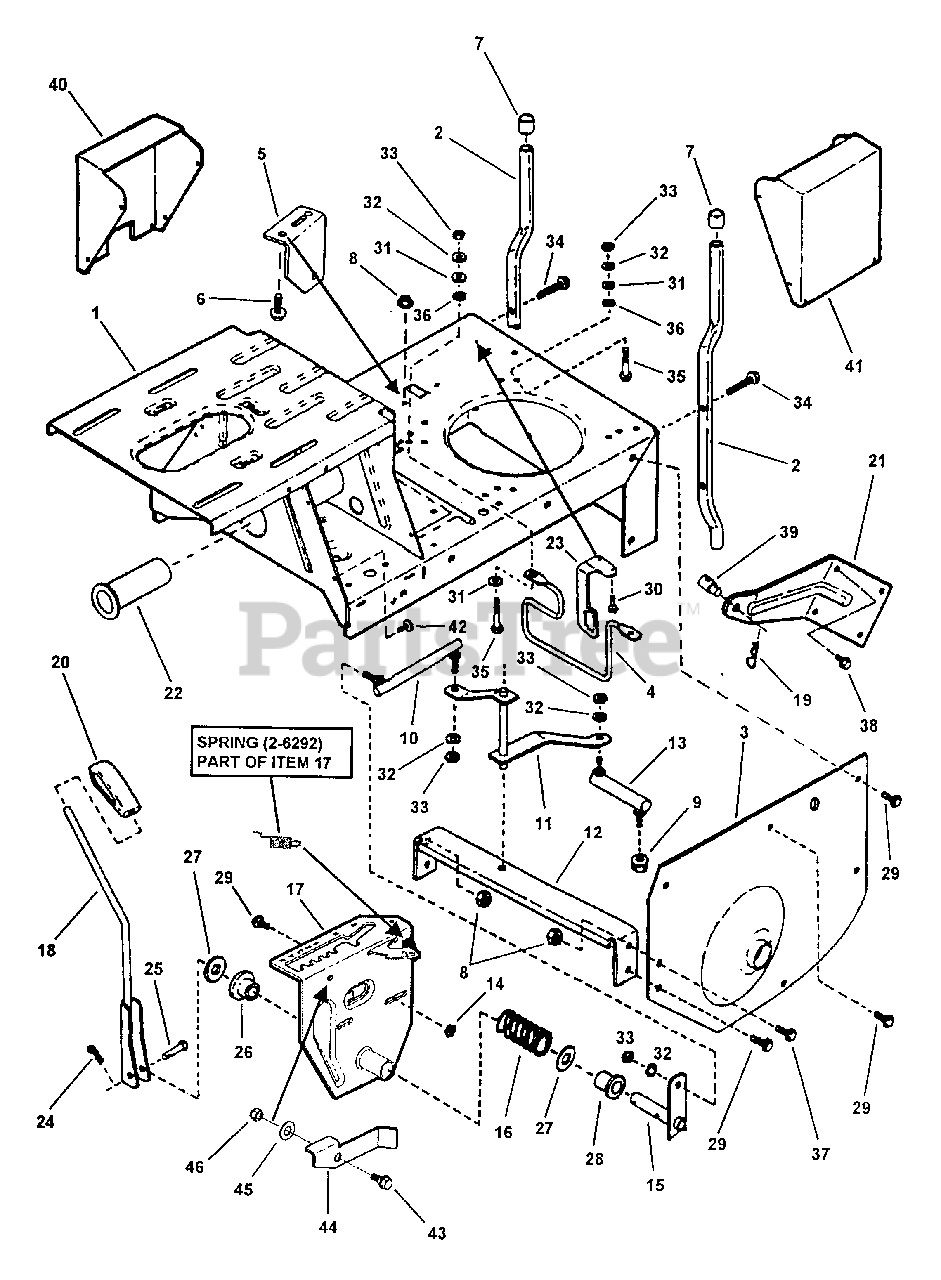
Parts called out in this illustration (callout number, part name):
1	CASE, Main (Standard)
2	BUMPER, Rear
3	FENDER, Left Hand
4	GUIDE, Belt
5	BRACKET, Drive Support
6	BOLT, 5/16-18 X 3/4" Hex Flange Lock
7	CAP, Bumper
8	NUT, 5/16-18 Hex Flange Lock
9	NUT, 5/16-24 Hex Flange Lock
10	LINK, Shift (Long)
11	ARM, Shift
12	BRACE, Cross
13	LINK, Shift (Short)
14	NUT, 5/16-18 Hex
15	ARM, Shift Handle
16	SPRING, Shift Handle
17	ASSEMBLY, Shift Detent
18	HANDLE, Shift
19	HAIRPIN, 3/32 X 1-1/2"
20	GRIP, Shift Handle
21	WING, Rear
22	BUSHING, Pilot
23	BRACKET, Switch
24	PIN, 3/32 x 3/4" Cotter
25	PIN, 1/4 x 1-3/4" Tapered Clevis
26	BUSHING, Nylon
27	WASHER, Thrust
28	BUSHING, Nylon
29	SCREW, 5/16-18 x 5/8" Self-Tap
30	SCREW, 10-32 x 1/4" Hex Washer Self-Tap
31	WASHER, 5/16" Flat
32	WASHER, 5/16" Split Lock
33	NUT, 5/16-24 Hex
34	SCREW, 5/16-18 x 1-1/2" Self-Tap
35	SCREW, 5/16-24 x 1-1/2" Hex Head Cap
36	RETAINER, 5/16 Bolt
37	SCREW, 5/16-18 x 3/4" Hex Head Cap
38	SCREW, 5/16-18 X 3/4" Hex Self-Tap
39	SWIVEL
40	COVER, Switch
41	COVER, Battery
42	FASTENER, 1/4 x 3/4" Ratchet
43	BOLT, 5/16-18 Shoulder
44	LEVER, Over-Ride
45	WASHER, 7/16" Flat
46	NUT, 5/16-18 Nyloc
